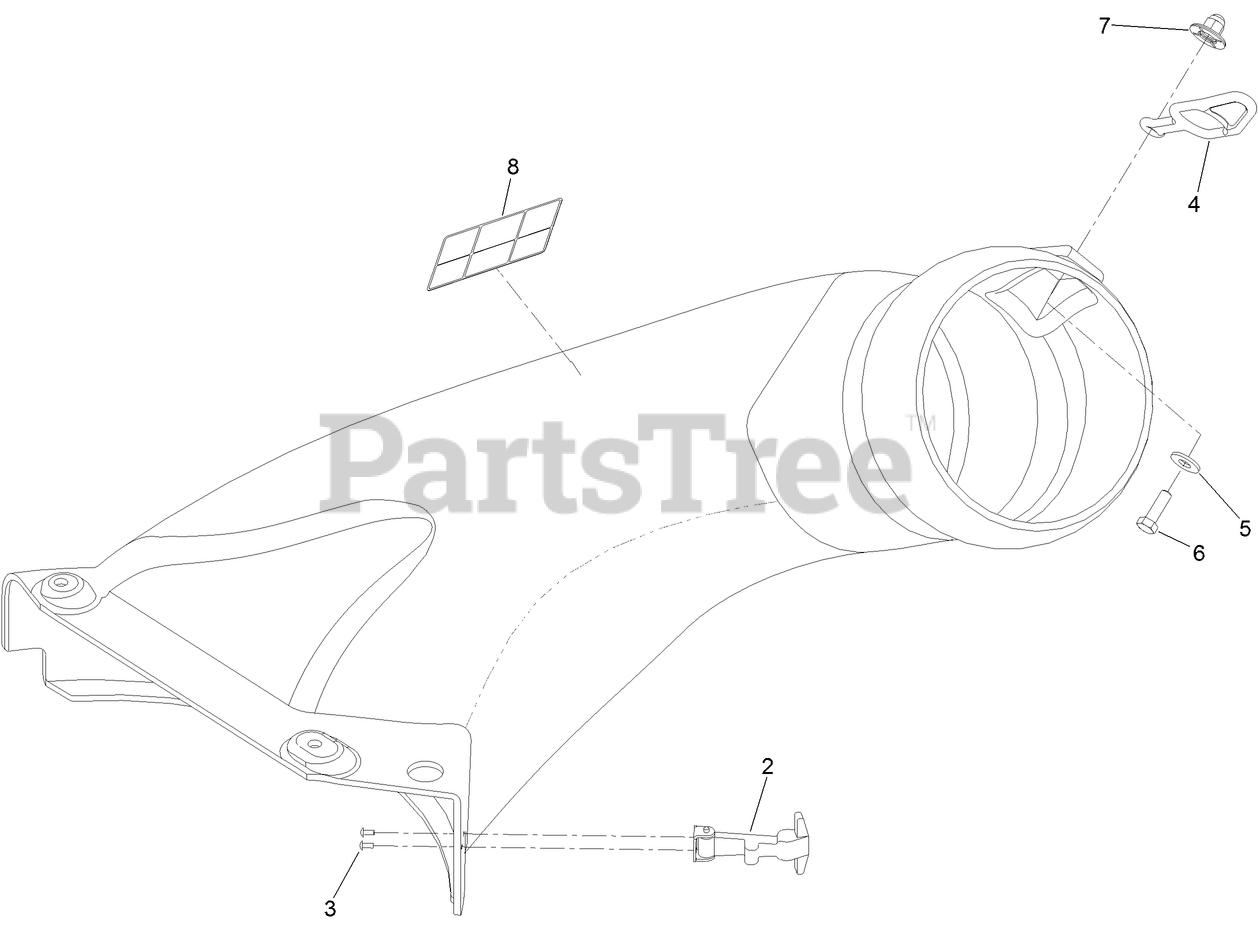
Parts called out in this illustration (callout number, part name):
2	HANDLE ASM
3	RIVET-POP
4	RETAINER-DUCT
5	WASHER-FLAT
6	SCREW-HH
7	NUT-IMPELLER
8	DECAL-DANGER
